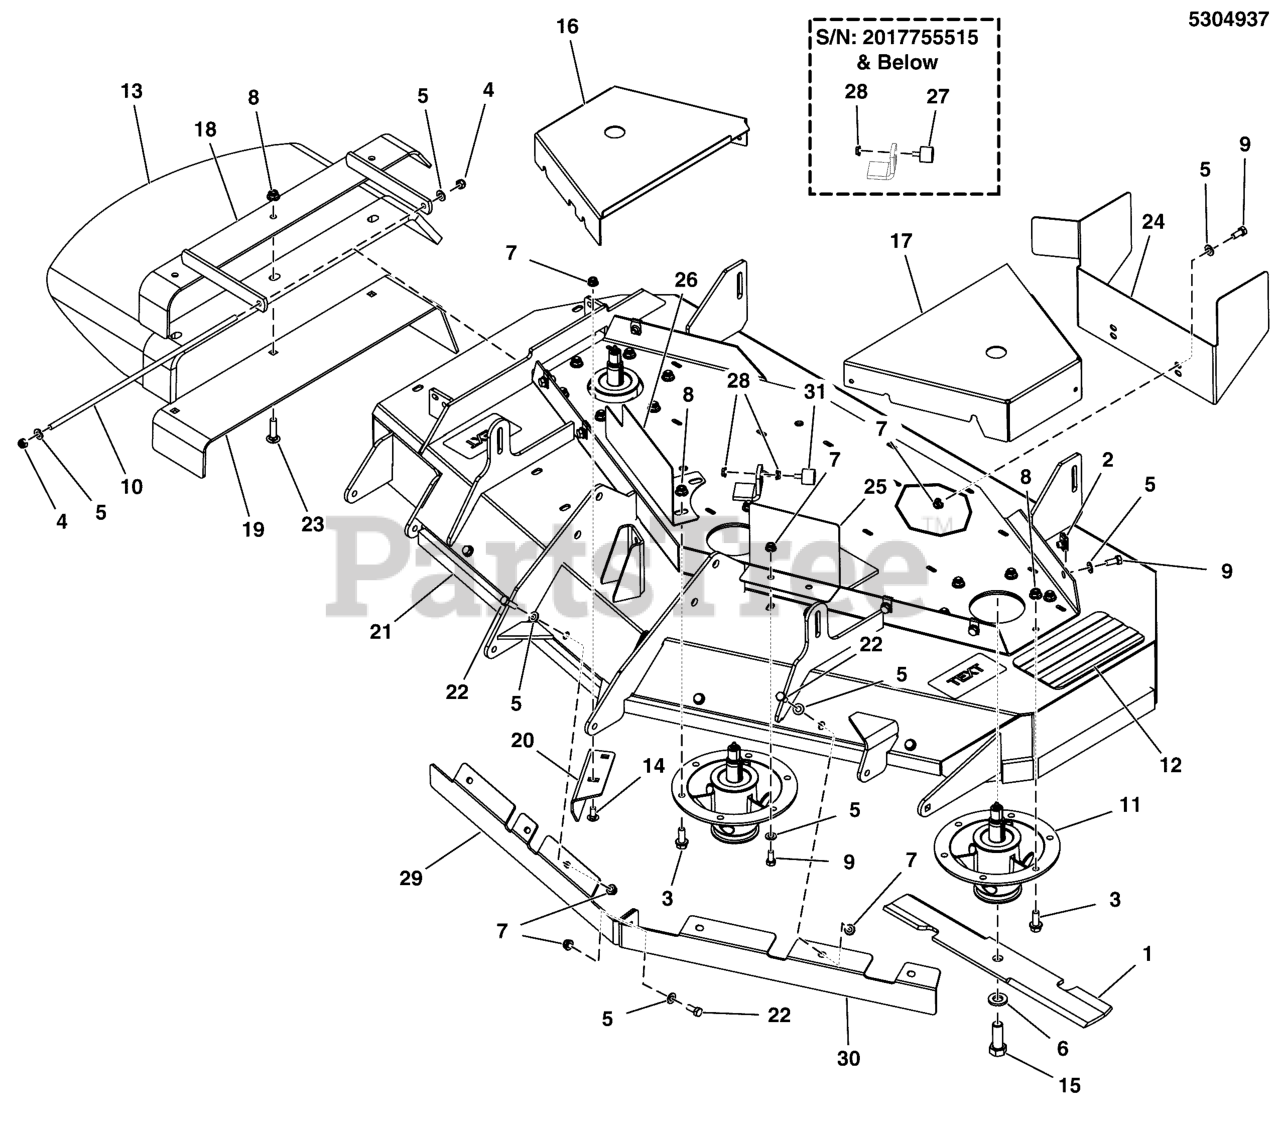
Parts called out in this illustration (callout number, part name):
1	BLADE, 18 X .25 X 2.5, 1 X 3.5 (SET OF THREE)
2	BODY CLIP, 5/16-18-7GA MATERIAL
3	BOLT, 3/8-16 X 1, FLANGE, GD 5, CZ
4	NUT, 5/16-24 HEX NYLON LOCK
5	WASHER, 5/16" SAE
6	WASHER, BLADE BOLT, 9/16" F436, CZ
7	NUT, 5/16-18 HEX NYLOCK FLANGE NUT
8	NUT, 3/8 - 16 HEX NYLOCK FLANGE
9	BOLT, 5/16-18 X 3/4 GD5
10	ROD, MOUNT, CHUTE, 61, CZ
11	SPINDLE ASSM, CAST IRON 8.0 - 6-BOLT
12	SAFETY WALK, 4.00 X 7.50
13	CHUTE, RUBBER DISCHARGE (5104442)
14	BOLT, 5/16-18 X 3/4, CARRIAGE, GD5, CZ
15	BOLT, 5/8-11 X 1-3/4 GD8
16	PLATE, DECK PULLEY GUARD, RH - RED
17	PLATE, DECK, PULLEY GUARD, LH - RED
18	WELD, CHUTE MOUNT, CE - BLK
19	SUPPORT, DISCHARGE CHUTE, CE - BLK
20	PLATE, DEFLECTOR, 52 DECK - BLK
21	DECK SHELL W/DECALS, F160ZCE-52 (5416312B)
22	BOLT, 5/16-18 X 1" GRD5 YZ
23	BOLT, 3/8-16 X 1-1/2, CARRIAGE, GD5, CZ
24	PLATE, REAR DECK BELT GUARD - RED
25	PLATE, FRONT DECK GUARD, LH - RED
26	PLATE, FRONT DECK GUARD, RH - RED
27	BUMPER, RUBBER, 1/4-20
28	NUT, 1/4-20 HEX SERR. FLANGE
29	BAFFLE, FRONT DISCHARGE RH - RED
30	BAFFLE, FRONT DISCHARGE LH - RED
31	BUMPER, RUBBER, 1/4-20 X 7/8" STUD
